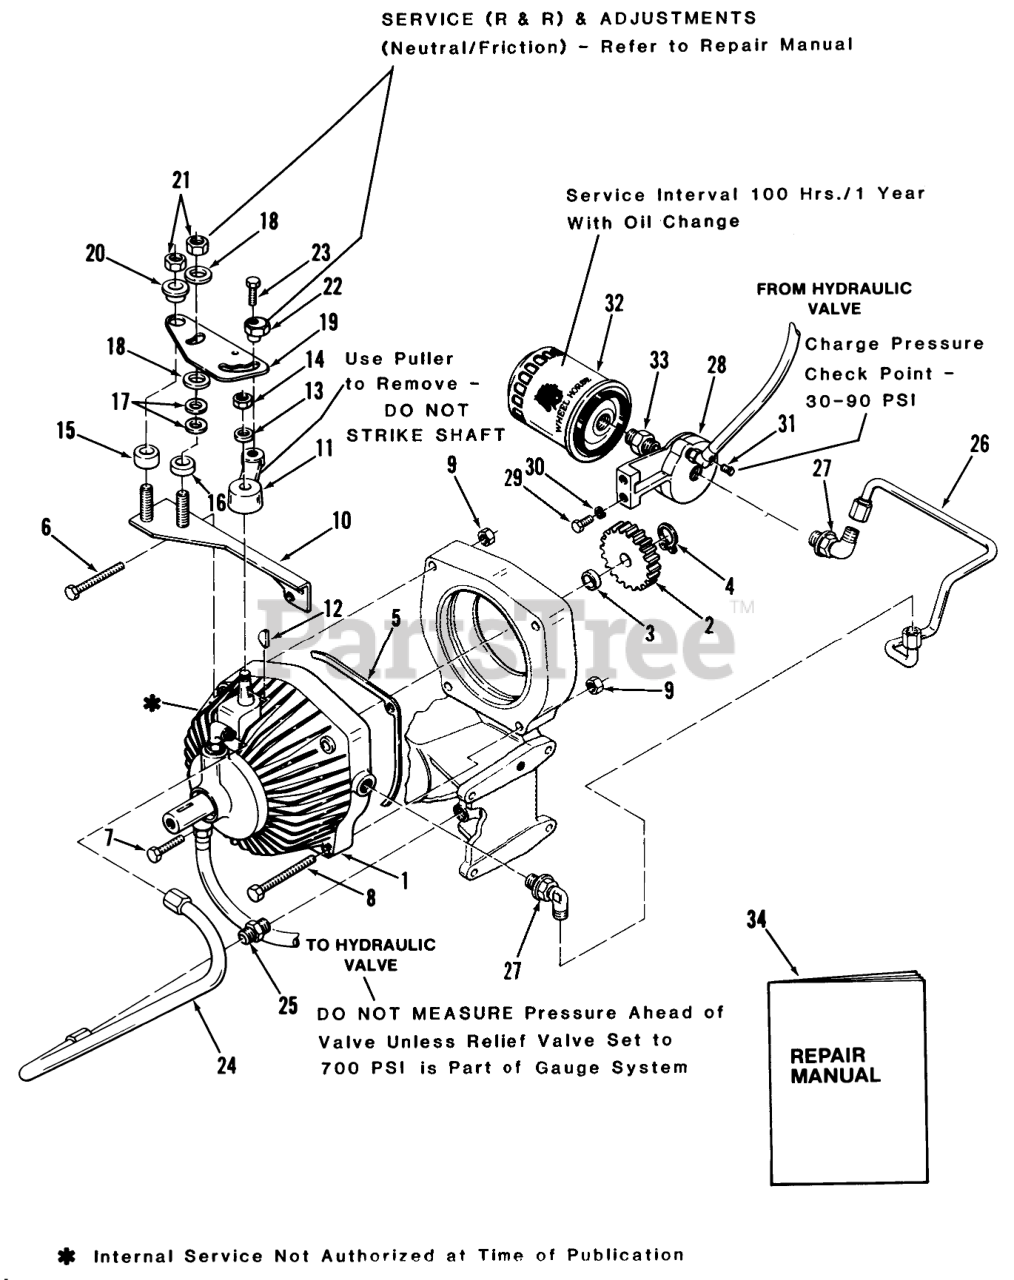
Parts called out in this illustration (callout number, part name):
1	Pump & Motor
2	GEAR 22T DRIVE
3	SPACER GEAR
4	SNAP RING- 5/8 EXT
5	GASKET
6	H H C S
7	Bolt
8	Bolt 3/8-16 x 6 1/2
9	Nut
10	ASSY-PLATE B
11	ARM-SPEED CONTROLB
12	Key #5 Woodruff
13	Washer
14	Eslok Nut
15	SPACER-PIVOT
16	SPACER-FRICTION
17	WASHER-SPRING DISC
18	FRICTION WASHER
19	CAM-SPEED CONTROL (NS)
20	CAM-SPACER
23	Bolt
24	ASSY-TUBE-SUCTION
25	FITTING-TUBE
26	ASM-TUBE FILTER OUTL
27	ELBOW
28	BASE-FILTER
29	Bolt
30	Lockwasher
31	PLUG 1/4 PIPE ALLEN
32	Filter-Oil
33	FITTING
34	Repair Manual
